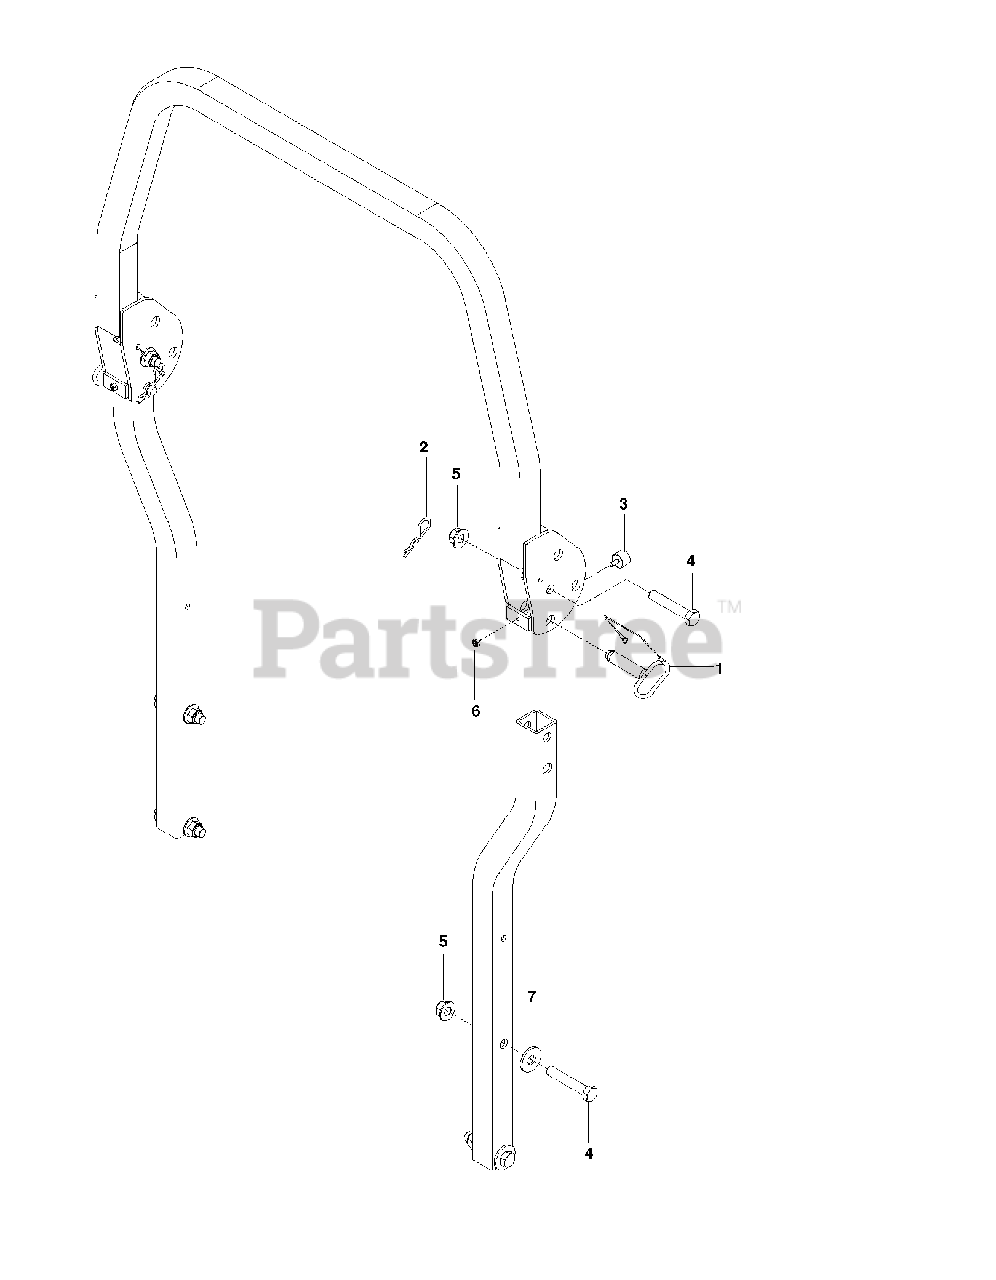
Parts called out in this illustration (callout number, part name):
2	PIN HAIR .148 X 2-15/16 #210
3	BUMPER, MALE STUD, 1/4-20
4	5/8-11 X 3-1/2 HHB GRADE 5
5	NUT 5/8-11 FLG NYLOC ZD
6	RP_NUT 1/4-20 NYLOC
7	WASHER, 5/8 FLAT
